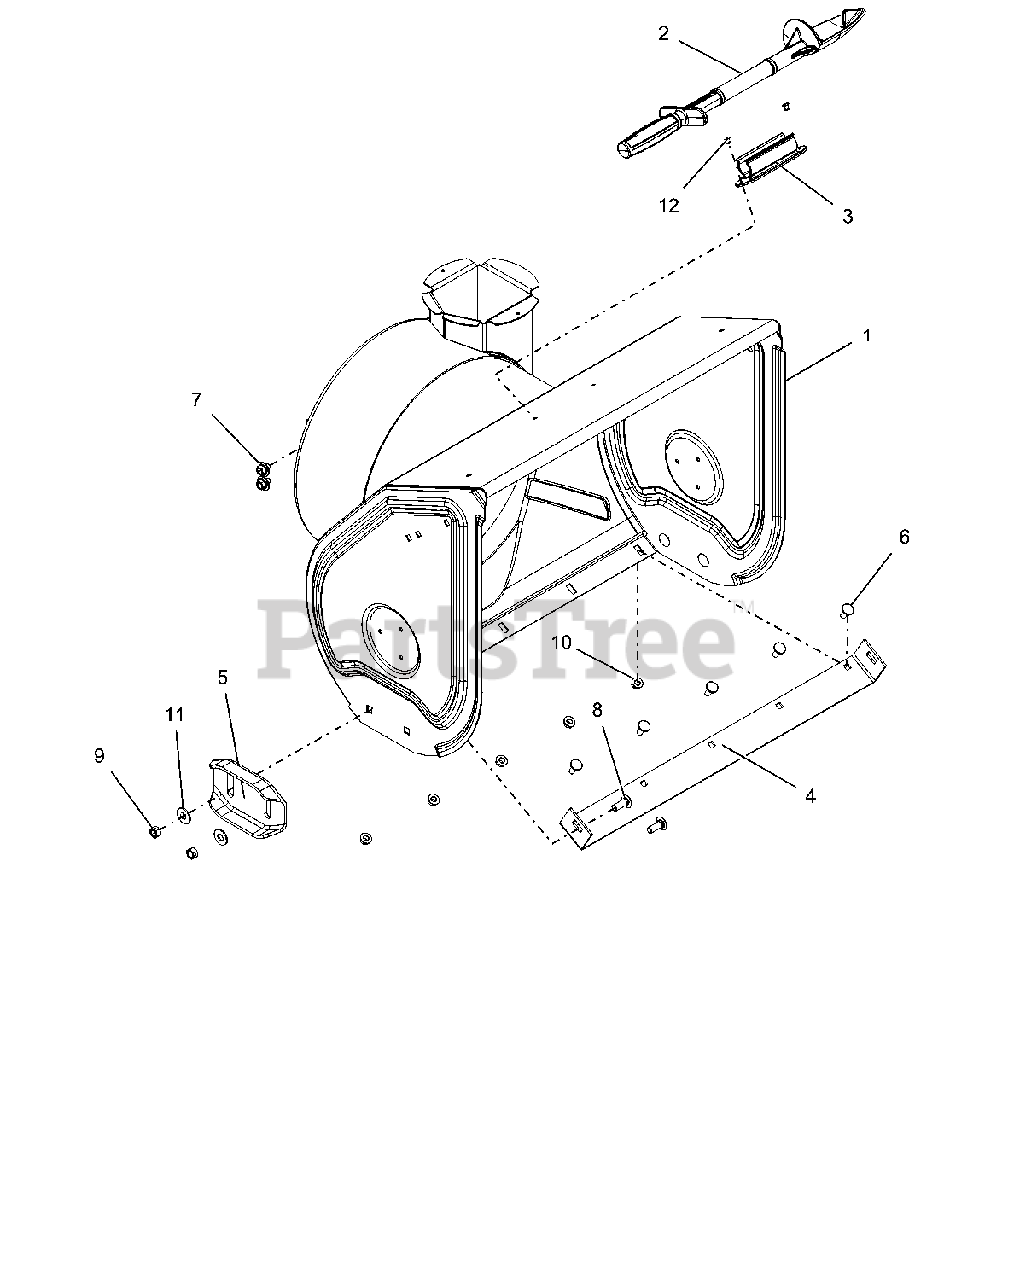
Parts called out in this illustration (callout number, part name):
1	BLOWER HOUSING W/DECAL 24"
2	DEVICE, SNOW CLEAN OUT
3	MOUNT, SNOW CLEAN OUT
4	BLADE, SCRAPER-24"
5	SKID SHOE, REVERSIBLE - ORANGE
6	BOLT, MODIFIED HEAD CARRIAGE
7	SCR-TAP.31-18X.50 HWH TR YWZ
8	@BLT-RDHDSHSQNK.38-16X1.0 G5YZ
9	@NUT-LK-CTR .38-16 YWZC
10	@NUT-LK-TOP-FLG .31-18 YWZC
11	@WSHR-FL-STL.438X1.00X.083 YWZ
12	RVT-POP .187 YZ
